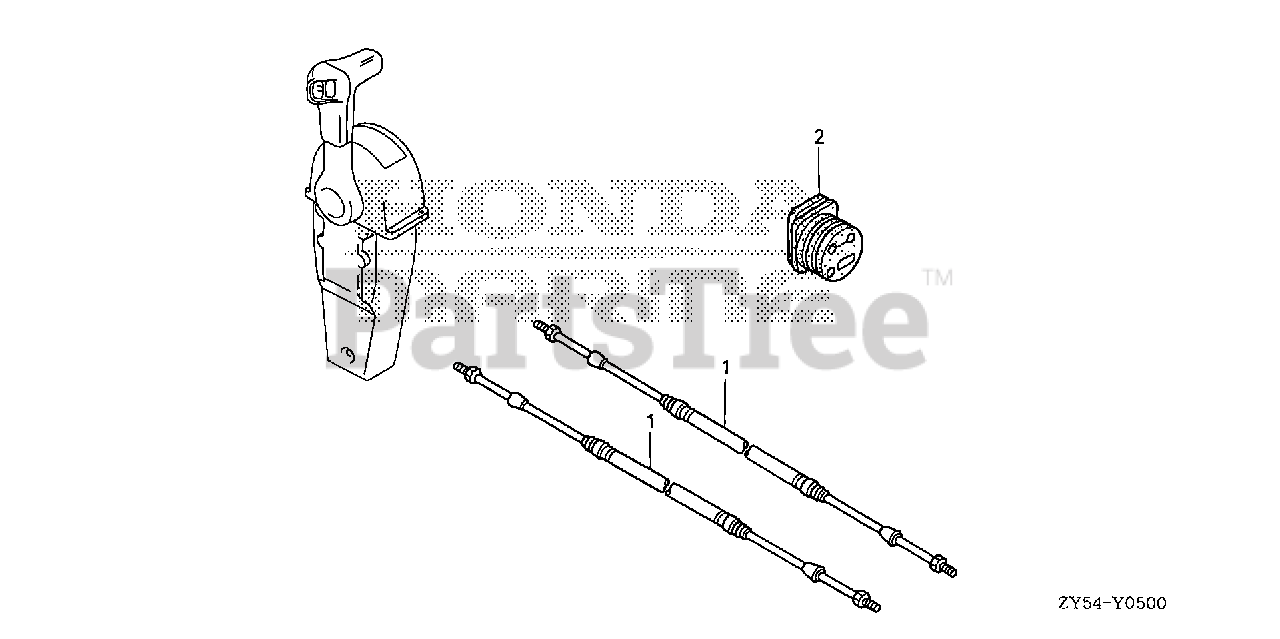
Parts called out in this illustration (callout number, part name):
1	CABLE ASSY., PUSH-PULL (33C-5FT)
1	CABLE ASSY., PUSH-PULL (33C-6FT)
1	CABLE ASSY., PUSH-PULL (33C-7FT)
1	CABLE ASSY., PUSH-PULL (33C-8FT)
1	CABLE ASSY., PUSH-PULL (33C-9F T)
1	CABLE ASSY., PUSH-PULL (33C-10FT)
1	CABLE ASSY., PUSH-PULL (33C-11FT)
1	CABLE ASSY., PUSH-PULL (33C-12 FT)
1	CABLE ASSY., PUSH-PULL (33C-13 FT)
1	CABLE ASSY., PUSH-PULL (33C-14FT)
1	CABLE ASSY., PUSH-PULL (33C-15 FT)
1	CABLE ASSY., PUSH-PULL (33C-16FT)
1	CABLE ASSY., PUSH-PULL (33C-17 FT)
1	CABLE ASSY., PUSH-PULL (33C-18 FT)
1	CABLE ASSY., PUSH-PULL (33C-19FT)
1	CABLE ASSY., PUSH-PULL (33C-20FT)
1	CABLE ASSY., PUSH-PULL (33C-21FT)
1	CABLE ASSY., PUSH-PULL (33C-22FT)
1	CABLE ASSY., PUSH-PULL (33C-23FT)
1	CABLE ASSY., PUSH-PULL (33C-24FT)
1	CABLE ASSY., PUSH-PULL (33C-25FT)
1	CABLE ASSY., PUSH-PULL (33C-26FT)
1	CABLE ASSY., PUSH-PULL (33C-27FT)
1	CABLE ASSY., PUSH-PULL (33C-28FT)
1	CABLE ASSY., PUSH-PULL (33C-29FT)
1	CABLE ASSY., PUSH-PULL (33C-30FT)
1	CABLE ASSY., PUSH-PULL (33C-31FT)
1	CABLE ASSY., PUSH-PULL (33C-32FT)
2	GROMMET, CASE (LOWER) (B)
